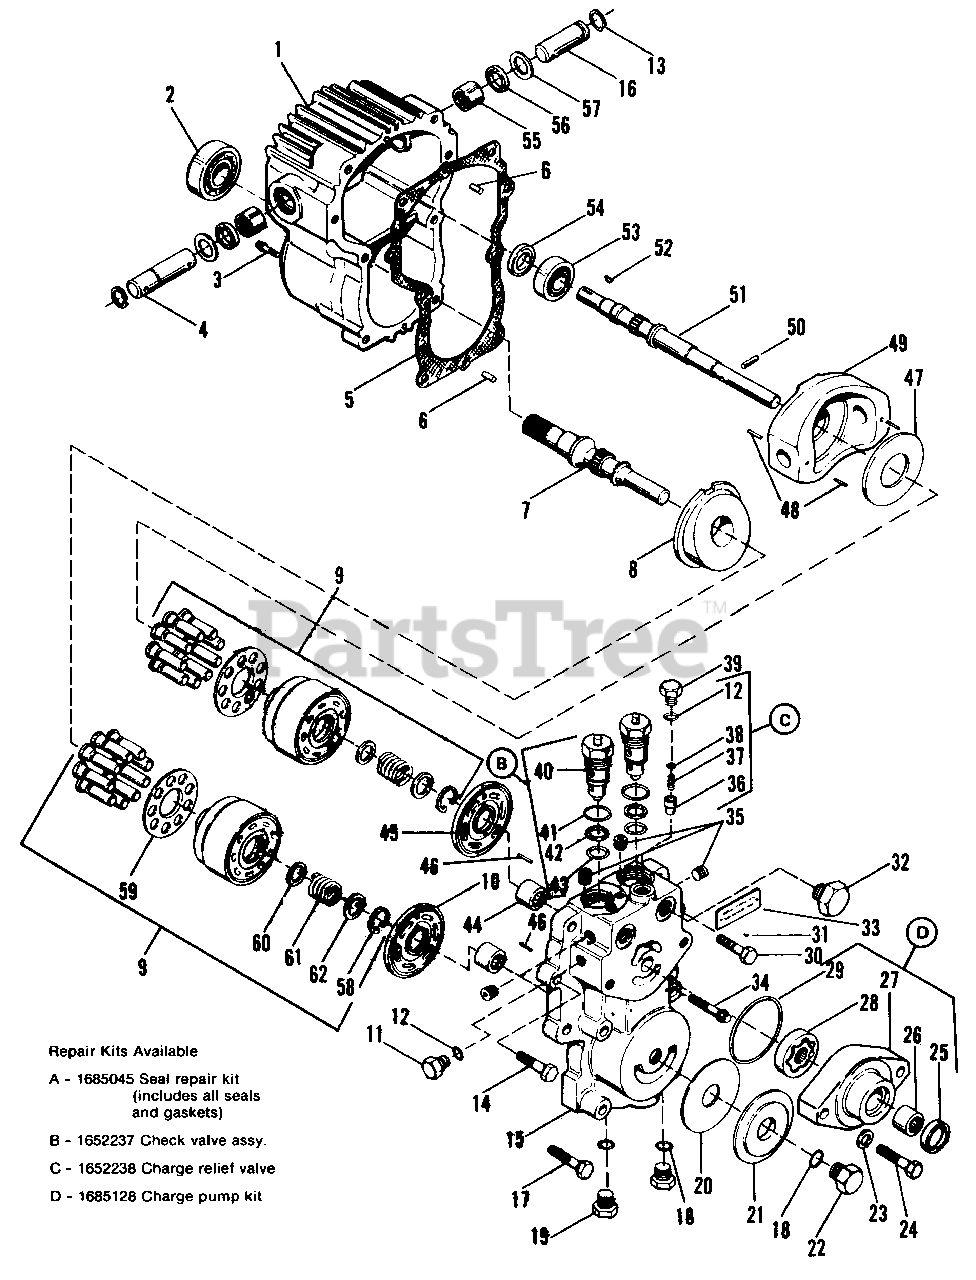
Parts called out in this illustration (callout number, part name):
2	BEARING, Ball
3	CAPSCREW, 12 Pt
6	PIN, Str. Headless
7	SHAFT, Motor
8	PLATE, Swash
9	CYLINDER BLOCK KIT
10	VALVE, Plate
11	PLUG, Hex Hd.
13	RING, Retaining
14	CAPSCREW, Hex Hd., 3/8-16 x 1-1/4
15	SECTION, Center
17	CAPSCREW, Hex Hd., 3/8-16 x 2
19	PLUG, Hex Hd.
21	COVER PLATE, Filter
22	PLUG, Special
23	WASHER, Flat
24	CAPSCREW, Hex Hd., 7/16-14 x 2
26	BEARING, Needle
27	HOUSING, Charge Pump
28	GEROTOR ASSY.
30	CAPSCREW, Hex Hd., 3/8-16 x 1-1/2
31	SCREW, Drive
32	PLUG, Str. Thd., Hex
33	PLATE, Name
34	CAPSCREW, 12 Pt.
36	CONE, Relief Valve
37	SPRING, Relief Valve
39	PLUG, Hex Hd.
40	CHECK VALVE ASSY.
42	RING, Back-up
44	BEARING, Needle
45	PLATE, Valve
46	PIN, Str. Headless
47	PLATE, Thrust
48	PIN, Coiled Spring
49	PLATE, Swash
50	PIN, Str. Headless
51	SHAFT, Pump
52	KEY, Woodruff
53	BEARING, Ball
55	BEARING, Needle
57	WASHER, Special
58	RING, Retaining
59	RETAINER, Slipper
60	WASHER, Front
62	WASHER, Rear
